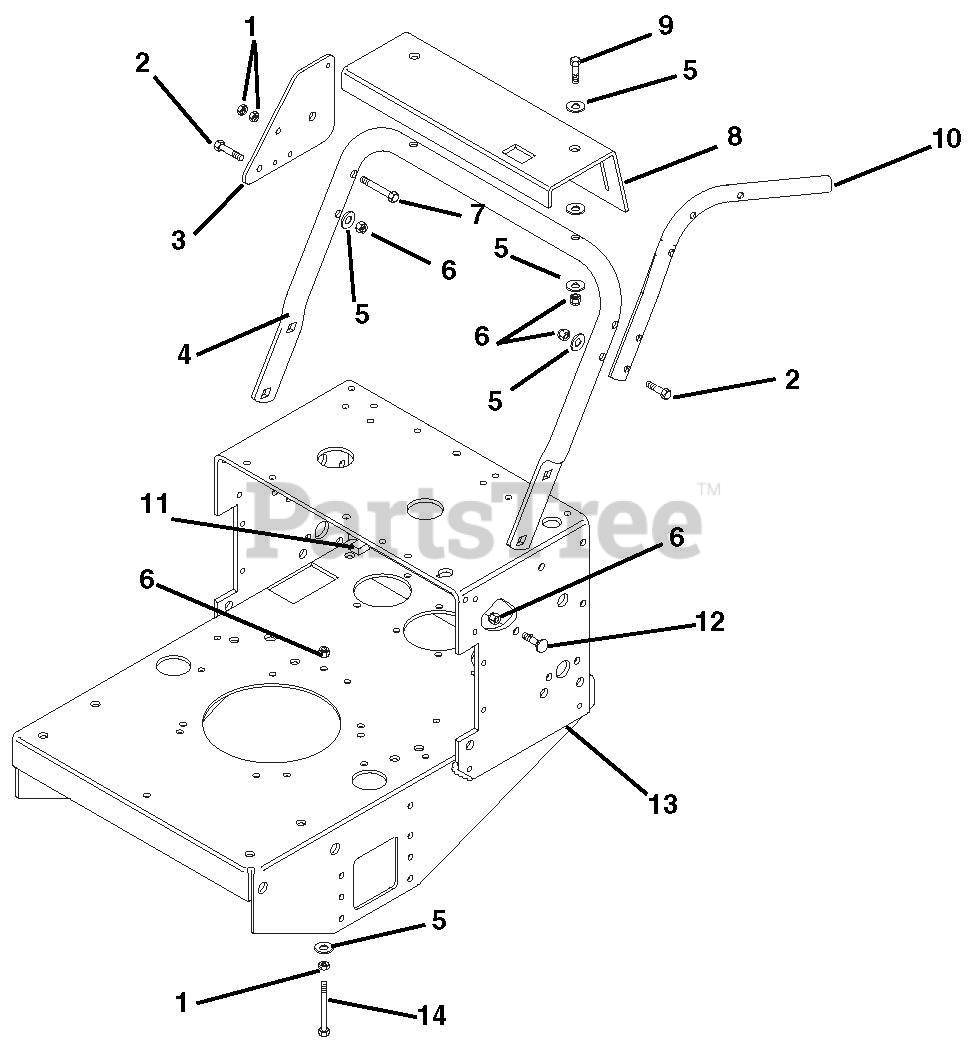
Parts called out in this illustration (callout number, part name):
1	@NUT-HEX .38-16 YWZC
2	@BLT-HEX .38-16X2.25 GR5 YWZC
3	PLT,SPEED CTL LEVER
4	TUBE, HANDLEBAR MOUNTING
5	@WSHR-FL-STL.406X.812X.065 YWZ
6	@NUT-LK-CTR .38-16 YWZC
7	@BLT-HEX .38-16X2.50 GR5 YWZC
8	INSTRUMENT PANEL, PRO-300
9	@BLT-HEX .38-16X2.25 GR5 YWZC
10	HANDLE, L.H.
10	HANDLEBAR, L.H.
10	HANDLE, R.H.
10	HANDLEBER, R.H.
11	STOP
12	@BLT-RDHDSQNK .38-16X1.00 G2YZ
13	WELDMENT, FRAME
14	@BLT-HEX .38-16X4.00 GR5 YWZC
